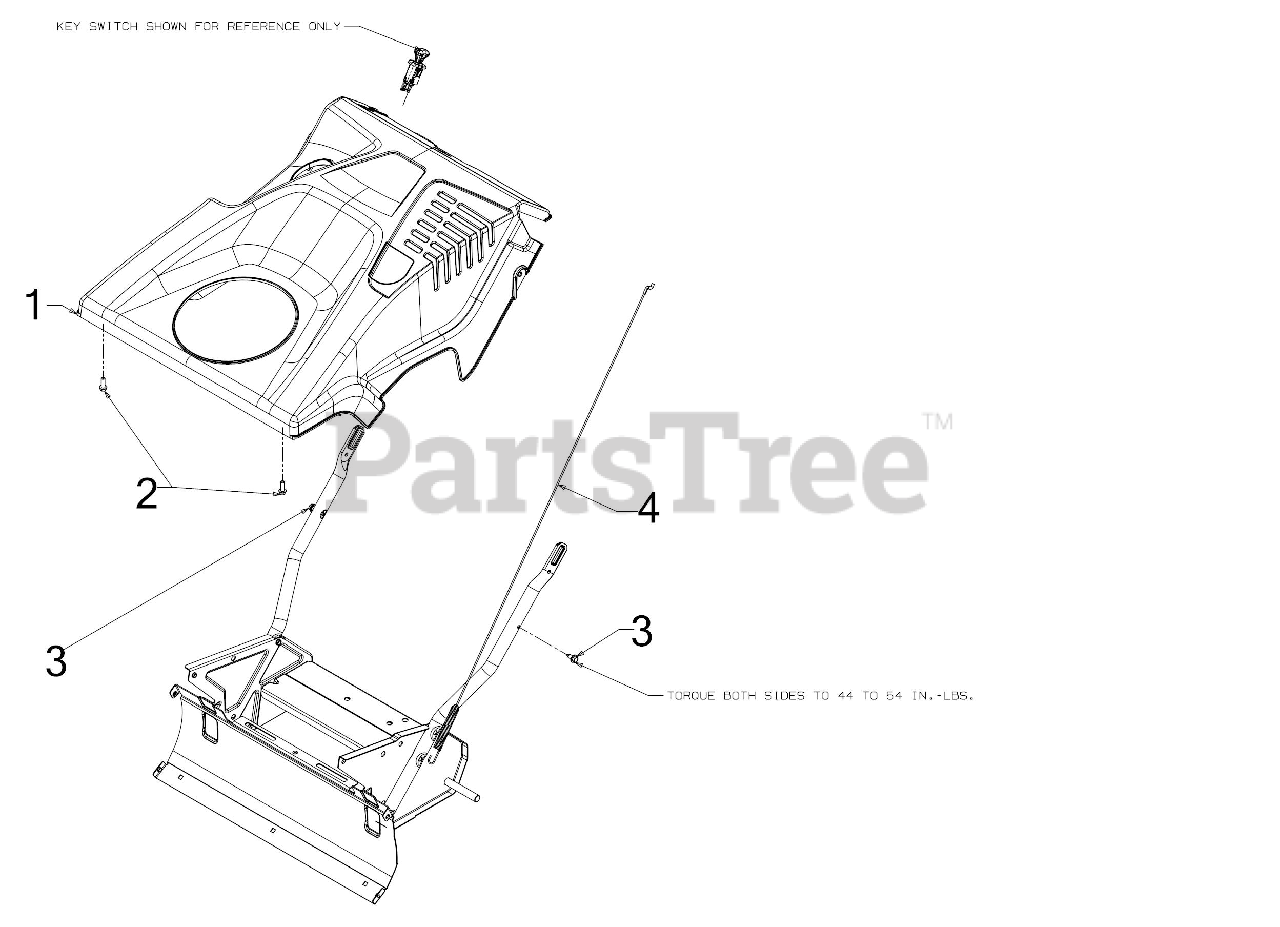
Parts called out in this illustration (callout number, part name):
1	COVER ASSEMBLY
2	SCREW 1/4-15 x .750
3	SCREW 1/4-20X.625
4	CLUTCH CABLE 35.03"
